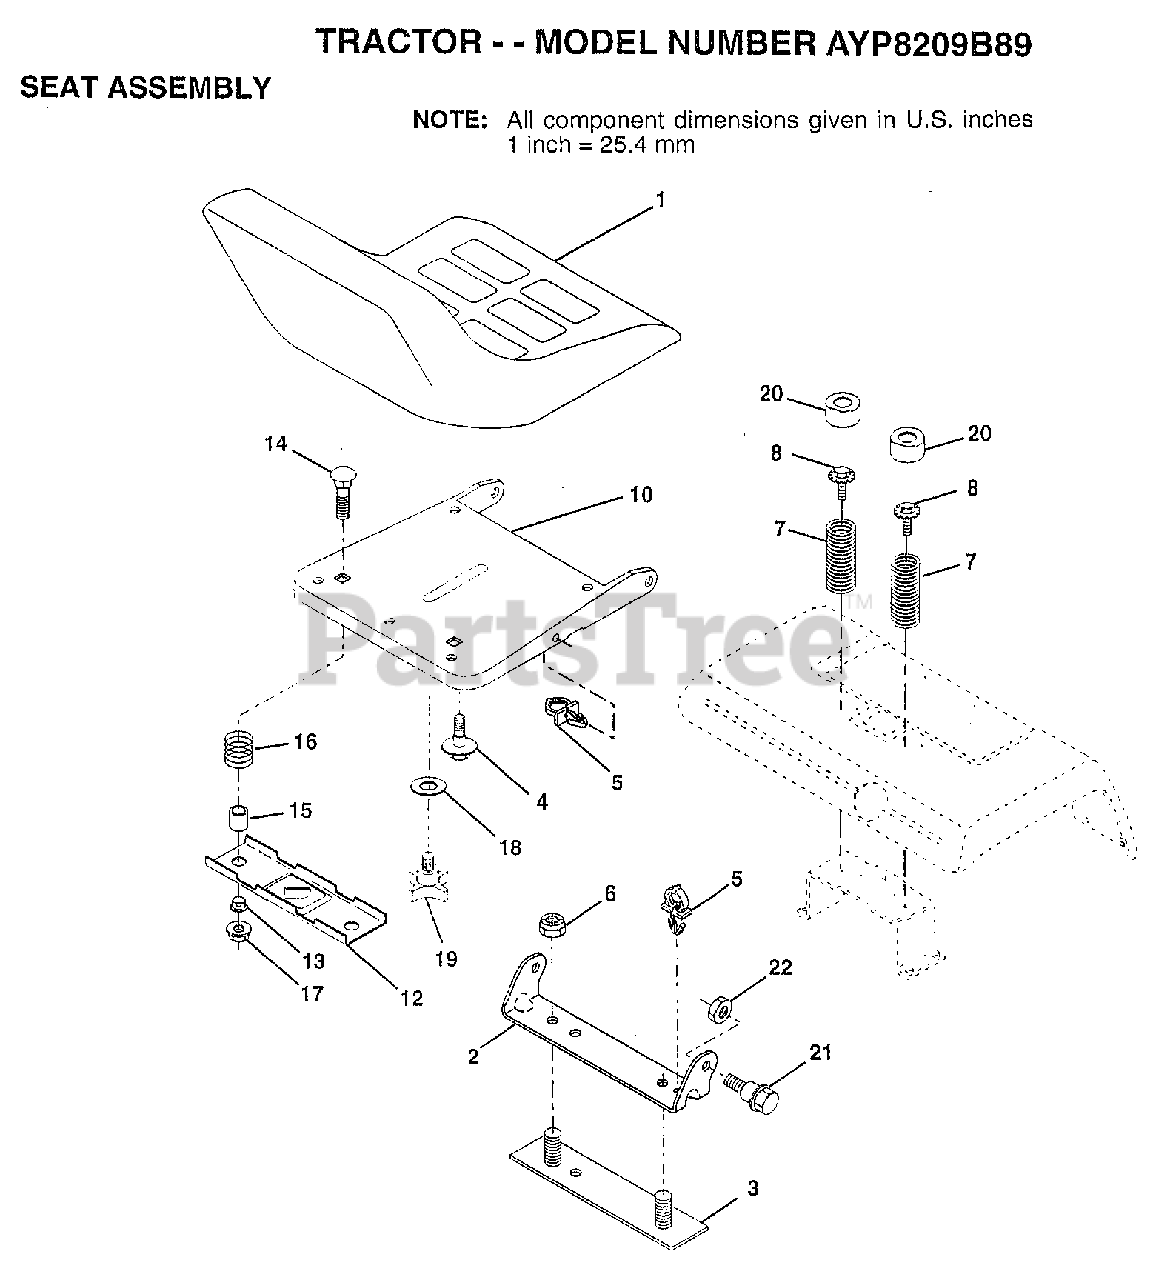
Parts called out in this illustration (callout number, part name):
2	BRACKET PVT SEAT
3	STRAP ASM FENDER
4	"BOLT,SHOULDER"
5	CLIP.PUSH-IN.HING
6	NUT
7	SPRING COMPRESSIO
8	BOLT.5/16-18.UNC
10	PAN-SEAT
12	BRKT SWITCH
13	BUSHING
14	BOLT-RD HD SQ NK
15	SPACER SPLIT
16	SPRING COMPRESSED
18	WASHER
19	"KNOB 1/2"" YT"
20	CAP SPRING
21	"BOLT,SHOULDER"
